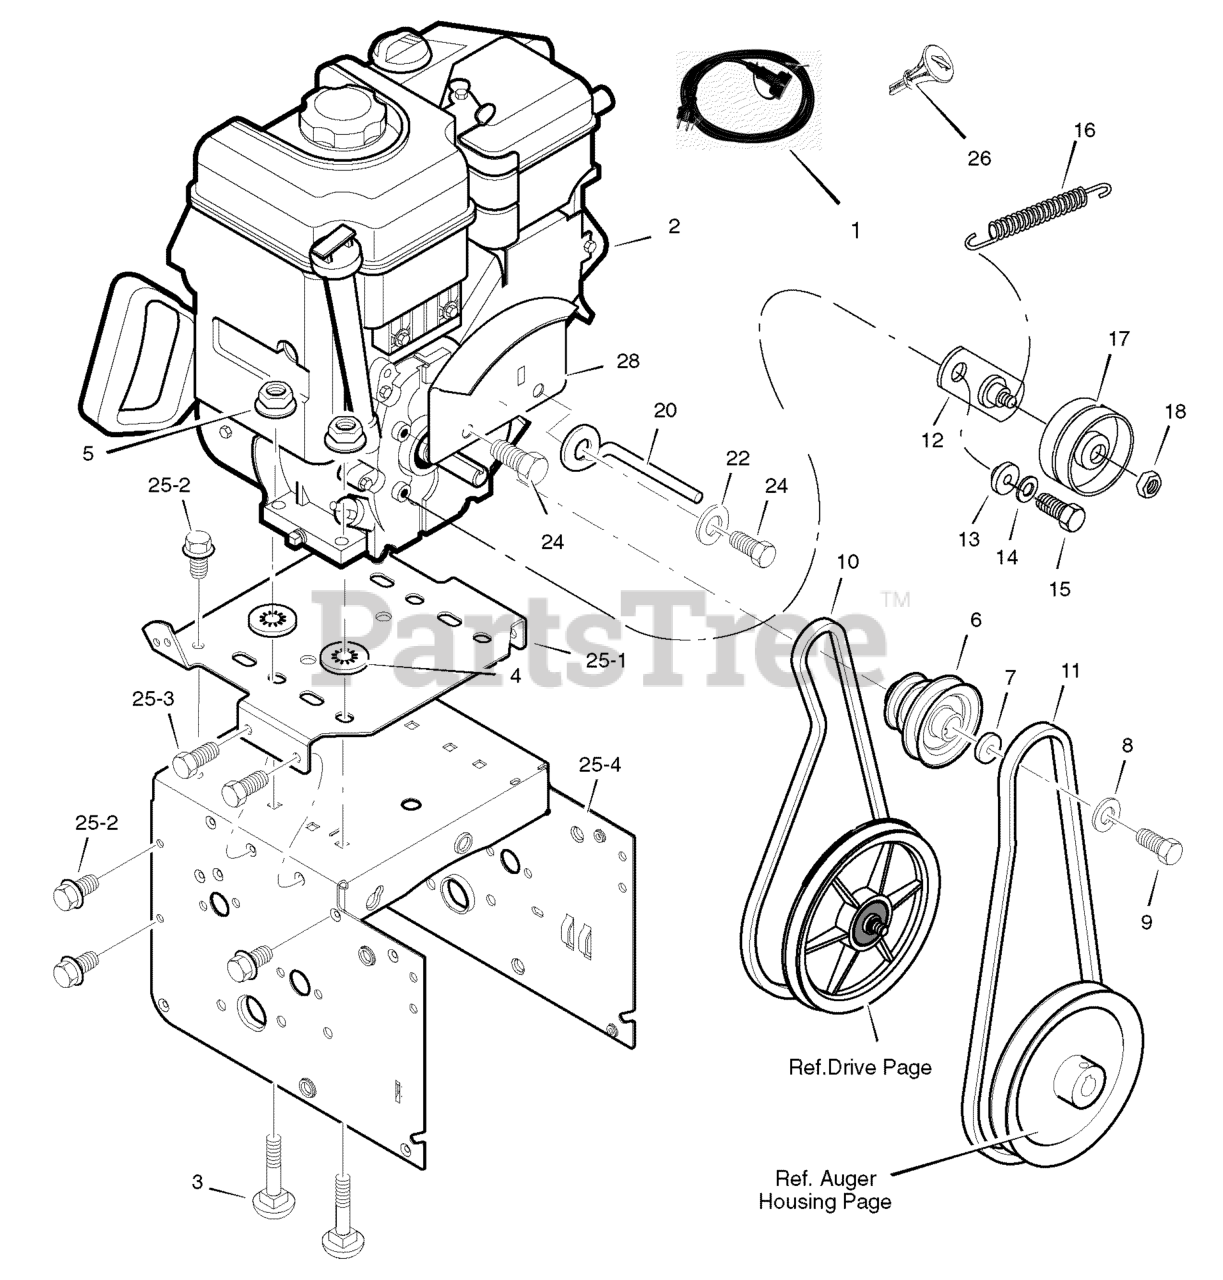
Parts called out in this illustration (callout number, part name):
1	CORD, STARTER
2	ENGINE
3	BOLT, CARRIAGE
4	RETAINER, PUSH
6	PULLEY, ENGINE
10	BELT, DRIVE V 4L
11	BELT, AUGER V 3L
12	BRACKET ASSEMBLY, IDLER
13	BUSHING, IDLER BRACKET
14	WASHER, SPLIT
15	SCREW 5/16-24 X .75
16	SPRING, IDLER TRACTION DRIVE
17	PULLEY, IDLER
18	NUT, JAM 3/8-16
20	GUIDE, ROD BELT
25	FRAME ASSEMBLY
25-1	PLATE, ENGINE
26	KEY, BRIGGS ENGINE
28	SHIELD, BRIGGS ENGINE
